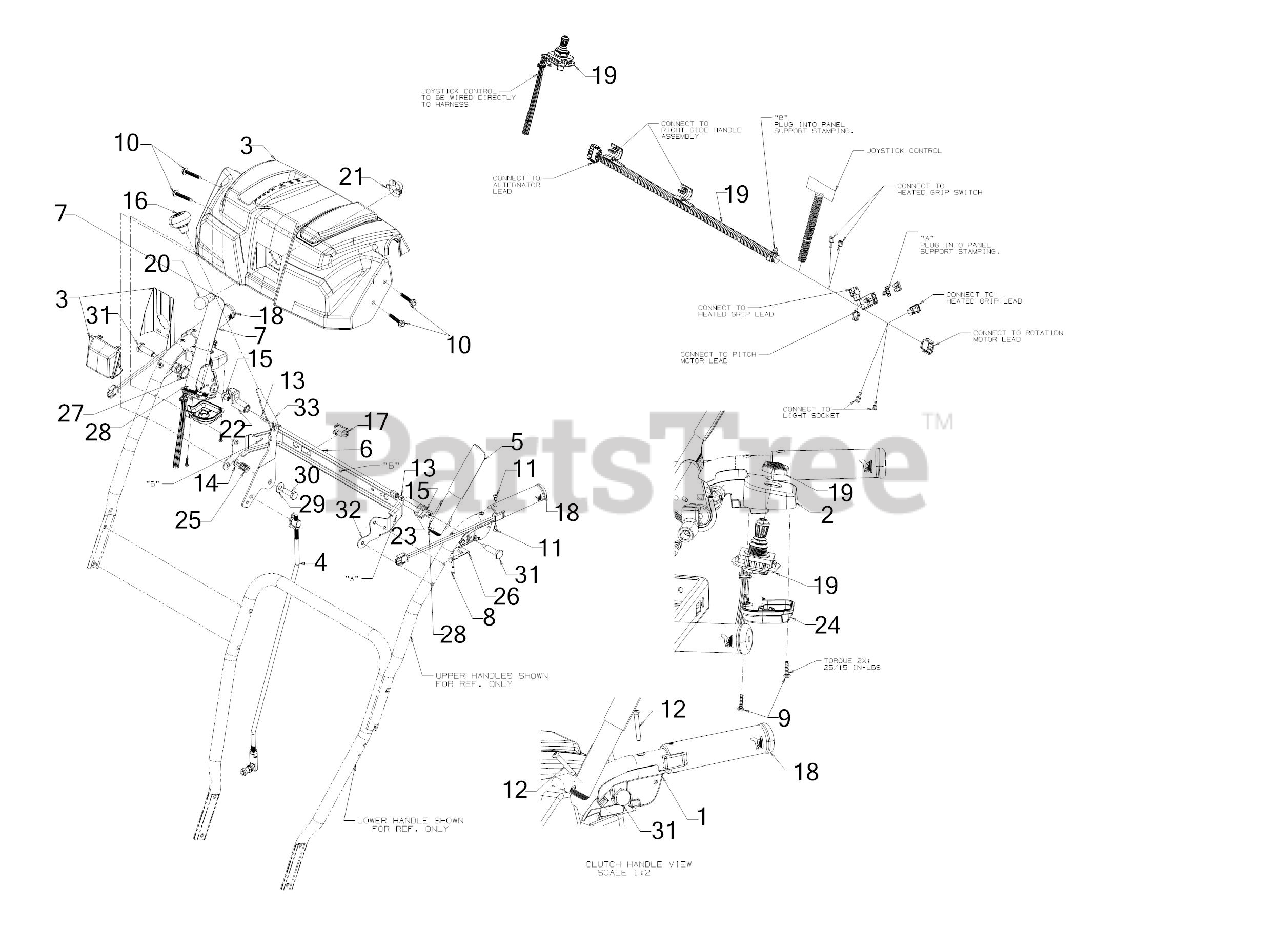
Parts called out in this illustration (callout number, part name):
1	CLUTCH LOCK HANDLE ASSEMBLY (LH)
2	CLUTCH LOCK HANDLE ASSEMBLY (RH)
3	4-WAY HANDLE PANEL ASSEMBLY
4	SHIFT ROD ASSEMBLY
5	HANDLE ASSEMBLY (LH)
7	ENGAGEMENT HANDLE ASSEMBLY (RH) (RED)
8	SCREW #8-16 x .50
9	SCREW .159 x .610
10	SCREW 1/4-20 x 1.625
11	SCREW #10-16 x .625
12	SCREW #10-24 x 1.375
13	SCREW 1/4-20 x .50
14	FLANGE LOCK NUT
15	HEX NUT W/PATCH
16	SHIFT KNOB
17	HEATED GRIP SWITCH
19	4-WAY ELEC/HEAT GRIP HARNESS
21	HEADLIGHT SOCKET
23	CLUTCH LOCK CAM
24	JOYSTICK HOUSING COVER
25	COMPRESSION SPRING
26	CLUTCH SPRING
27	TORSION SPRING
28	RUBBER BUMPER
29	FLAT WASHER
30	SHOULDER SCREW
31	SHOULDER SCREW .437 x 1.345 1/4-20
32	HANDLE SUPPORT BRACKET
